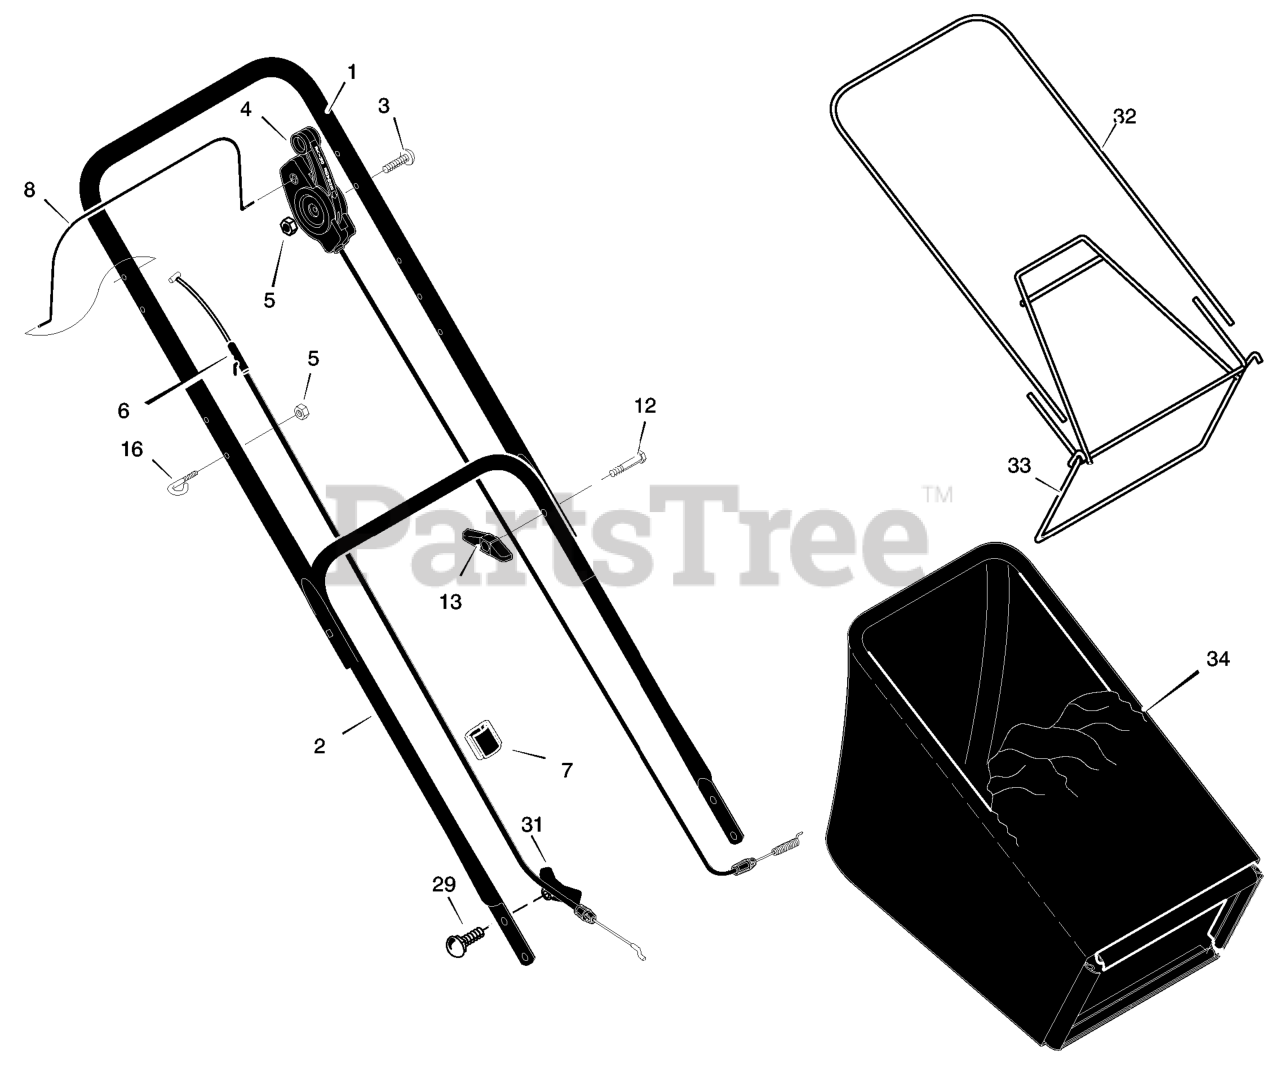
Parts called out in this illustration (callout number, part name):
1	Handle, Upper
2	Handle, Lower
4	Control, Drive
5	Locknut
6	Cable, Stop
7	Fastener, Cable
8	Lever, Stop
13	Knob
16	Guide, Rope
29	Bolt, Carriage
31	Knob, Plastic
32	Tube, Bag
33	Frame Assembly
34	Bag, Cloth
